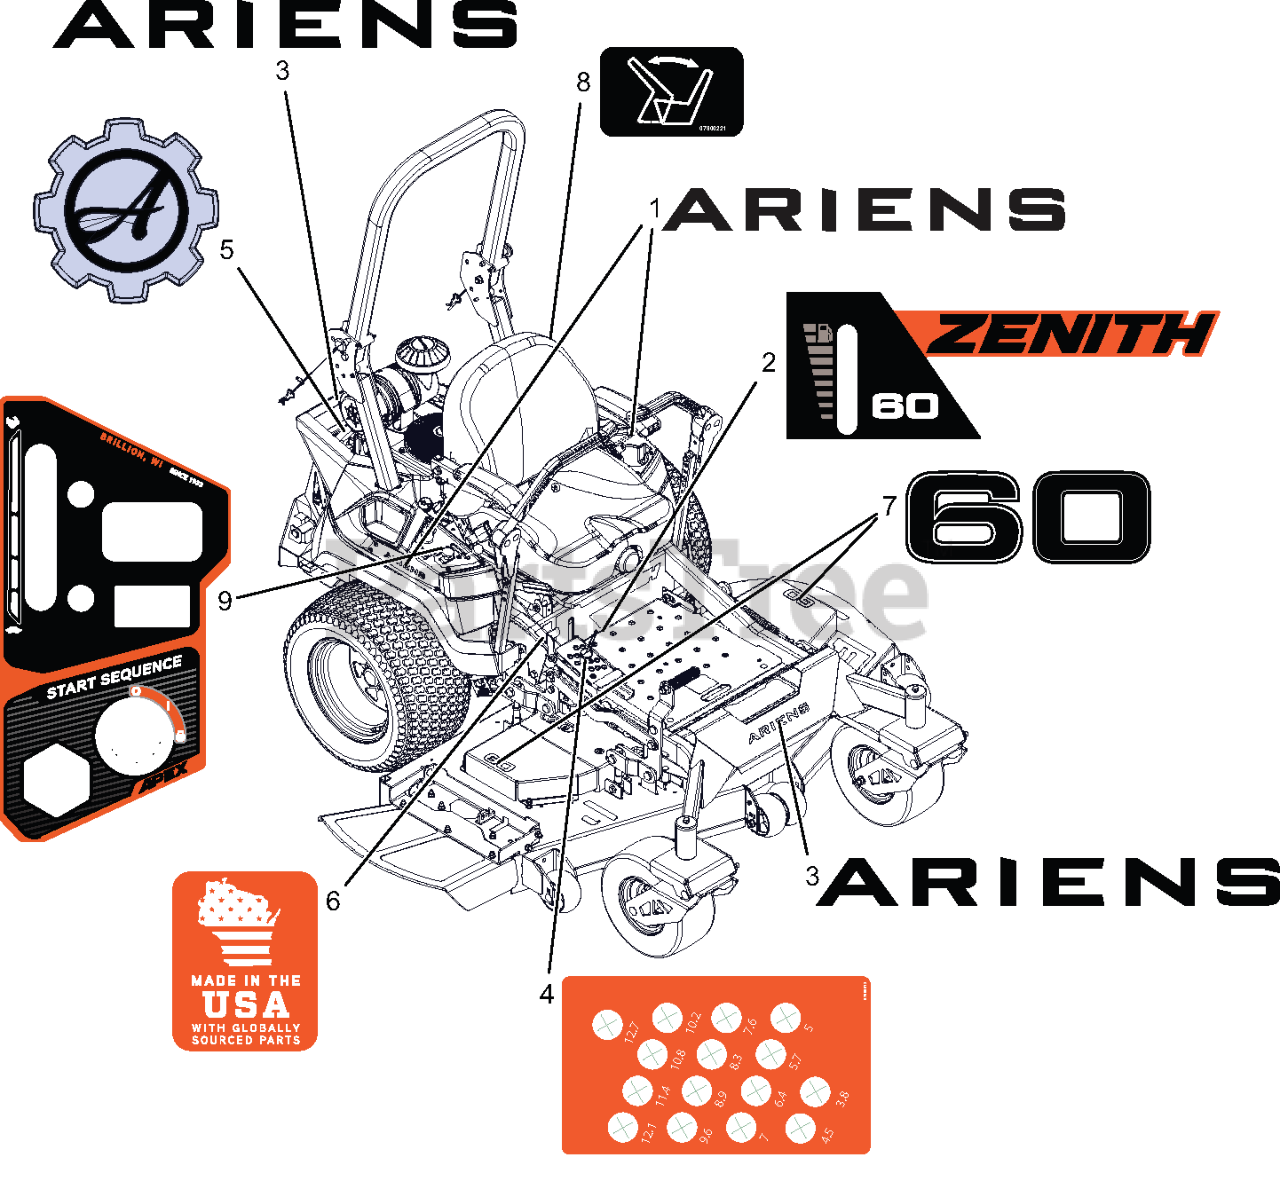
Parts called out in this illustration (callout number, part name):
1	DECAL- ARIENS 6.000" BLACK
2	DECAL- ZENITH 60 KICKPLATE
3	DECAL- ARIENS 9.625" BLACK
4	DECAL, APEX HOC METRIC
5	DECAL- ARIENS GEAR BADGE
6	DECAL- MADE IN USA
7	DECAL- DECK 60
8	DECAL - SEAT RELEASE
9	DECAL- DASH -APEX & ZENITH
